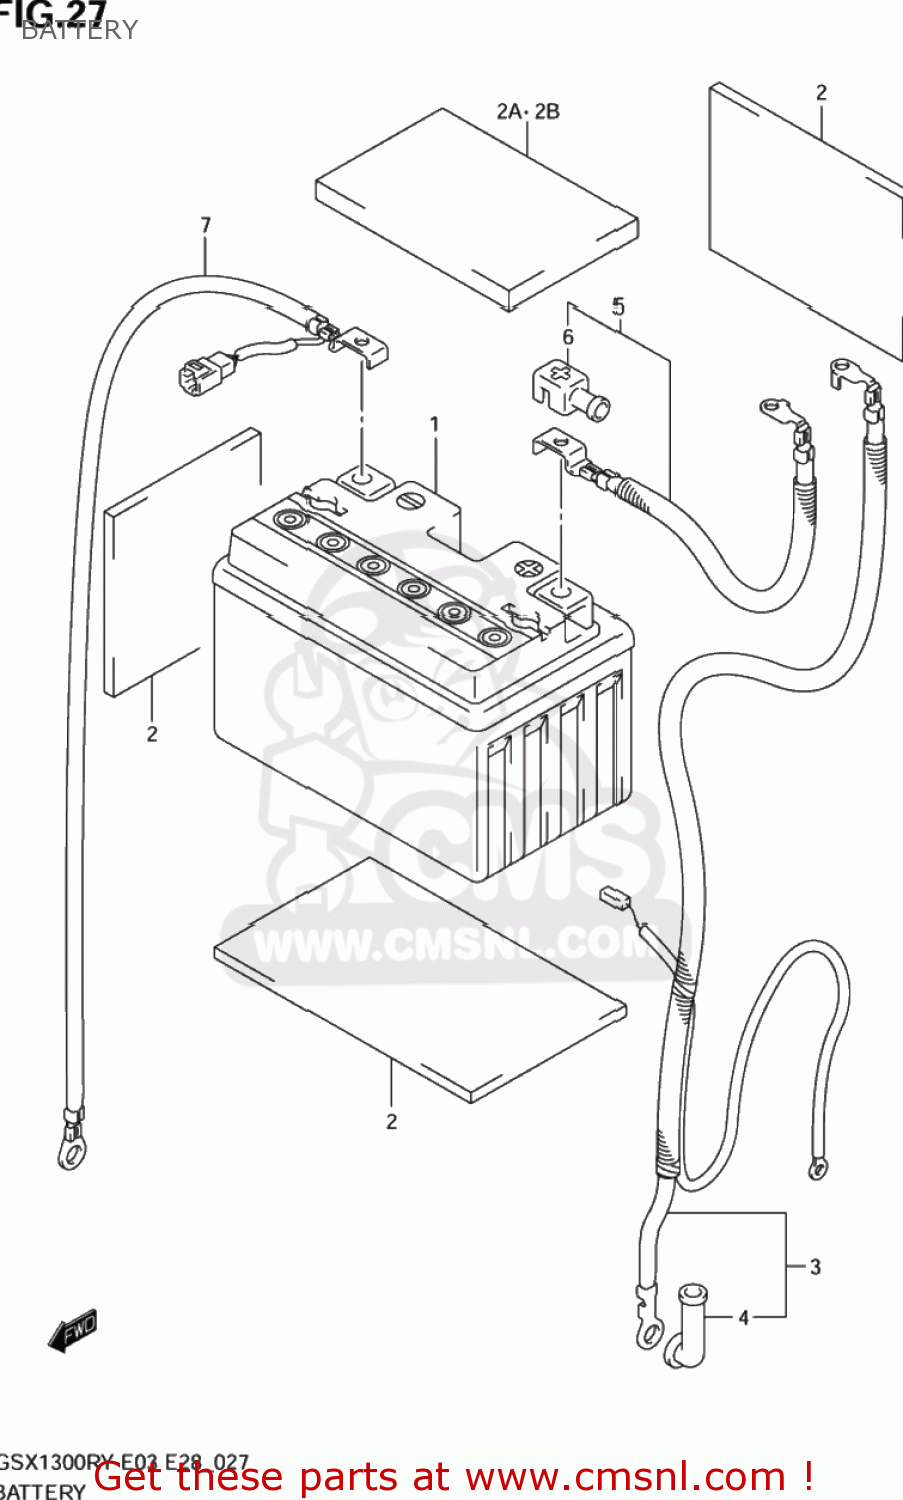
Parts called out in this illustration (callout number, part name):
1	BATTERY ASSEMBLY (12V) YT1
2	PROTECTOR(170X95X3.0)
2A	PROTECTOR(40X85X5)
2B	PROTECTOR,BATT
3	WIRE,STARTER MOTOR
4	CAP,STARTER MOTOR LEAD
5	WIRE,BATTERY PLUS
6	CAP,BATTERY PLUS
7	WIRE,STARTER MOTOR
